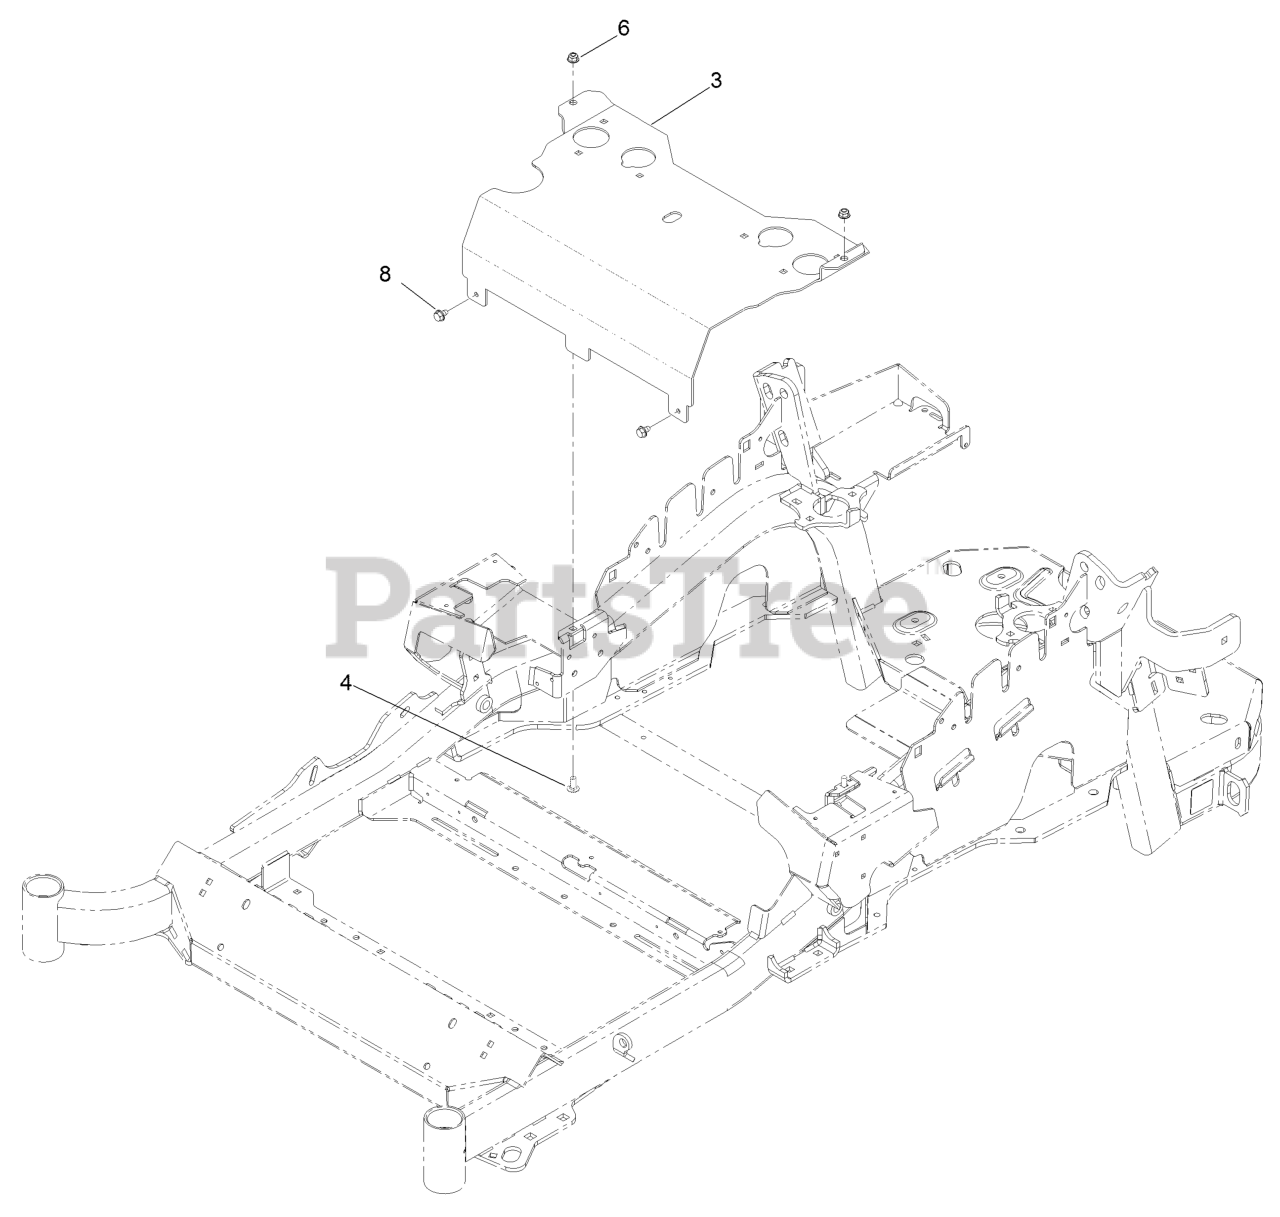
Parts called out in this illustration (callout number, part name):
3	Panel-Front, Seat Mount
4	SCREW-CARR
6	NUT-HF, NI
